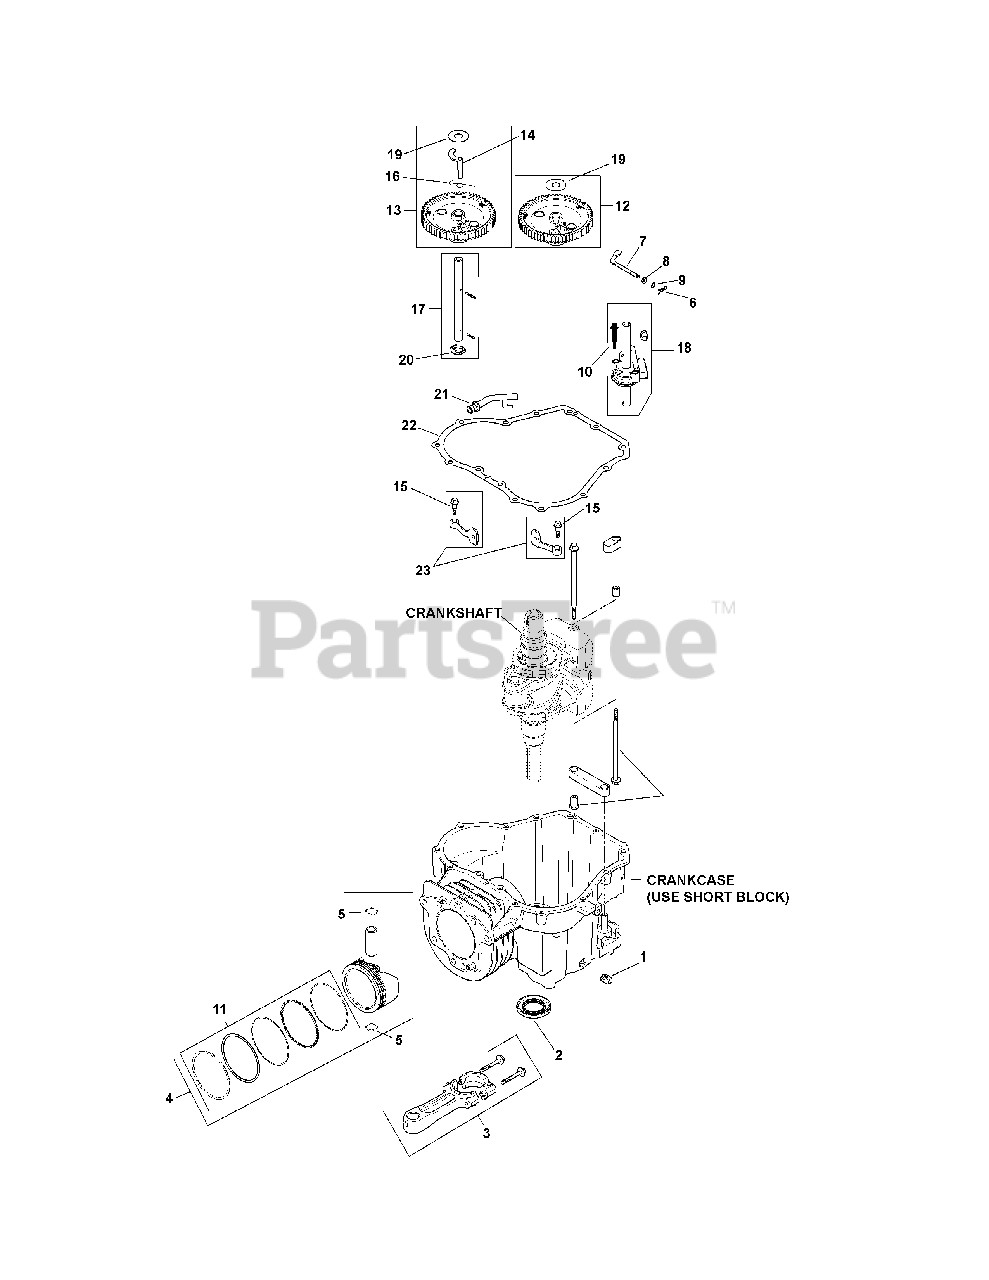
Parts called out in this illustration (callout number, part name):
1	Sq. Hd. Pipe Plug, 3/8
3	Connecting Assembly Rod
4	Piston w/ Ring Set Kit, 94mm
5	Piston Pin Retainer
6	Hitch Pin Clip
7	Governor Cross Shaft
8	Flat Washer, 6 mm
9	Flat Washer, 1/4
10	Shd. Thd. Frm. Screw
11	Ring Set, 94MM
12	Cam Lobe Assembly
13	Cam Gear Assembly
15	Shd. Thd. Frm. Screw, M6 X 1 X 26
17	Cam Center Shaft Kit
19	Thrust-ACR Washer
20	Thrust Washer
21	Drainback Tube
22	Closure Plate Gasket
23	Cam Lever Assembly Kit
